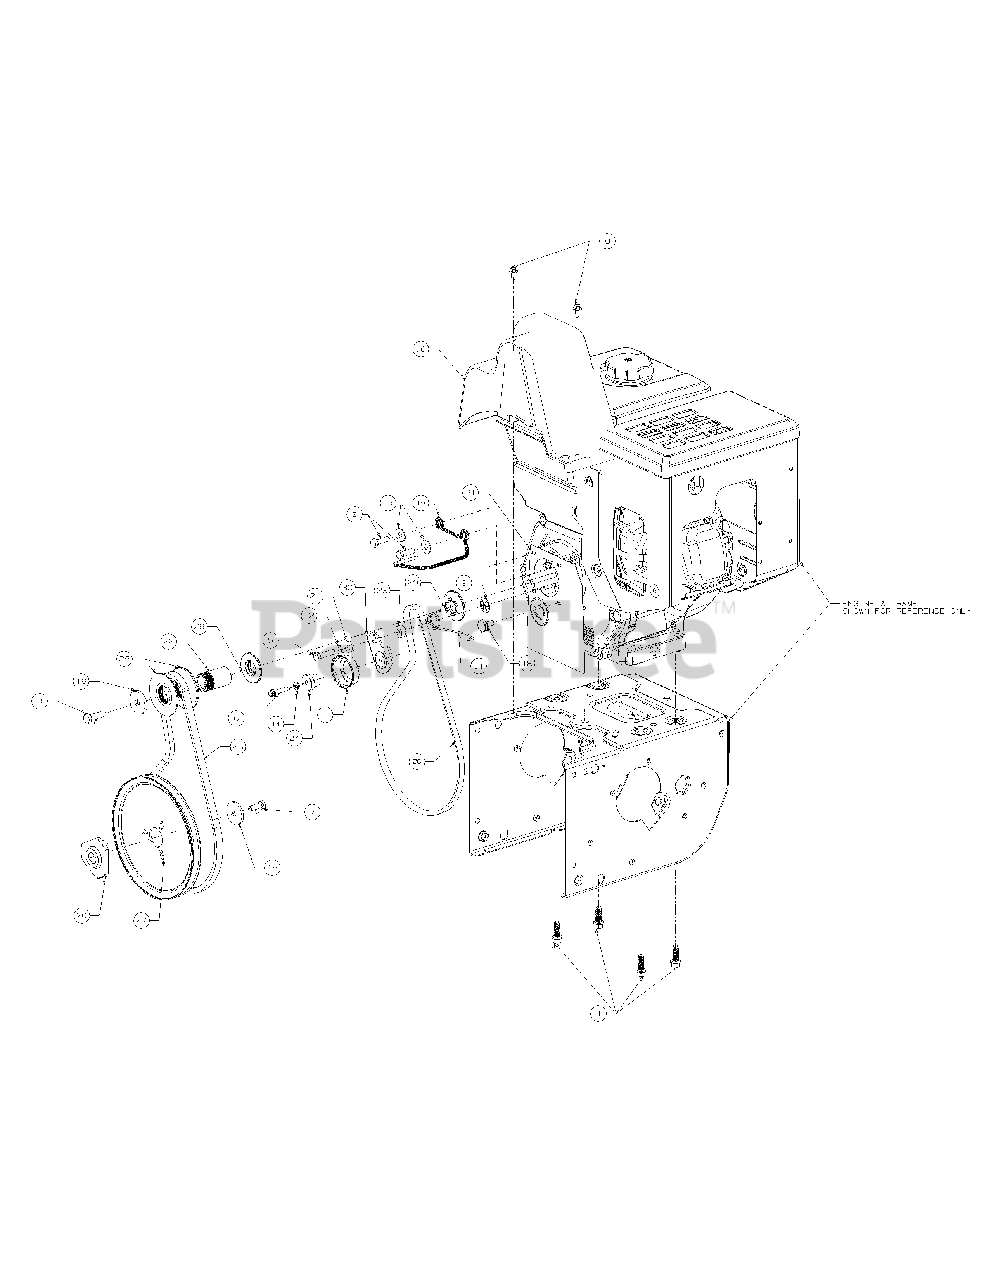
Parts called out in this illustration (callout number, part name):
1	Pulley Asm:Idler
2	Hhcs-5/16-24 X 1.0
3	Screw 3/8-24X1.25
4	Screw-Hex
5	Screw-Hex 5/16-24
6	Screw-Hex 1/4-20 X
7	Screw-Hex Cap 5/1
8	Screw Hex.Wash.Hd
9	Nut-Push On
10	Cover-Belt 4 Way
11	Spring-Torsion
12	Washer-Lock 5/16
13	Washer-Fl
14	Washer-Lock
15	Washer-Fl
16	Washer-Flat .45 X
17	Grease-
18	Screw-Shoulder
19	Guide-Belt
20	Pulley-Adapter .75
21	Spacer-Shoulder
22	Spacer-Pulley
23	Spacer-Idler Brkt
24	Spacer:Shoulder
25	Belt-.500 X 37.00 Lg
26	Belt-V Type 3/8 X 35.68"
27	Pulley-Auger 8.1 O
28	Pulley-Half 4L V
29	Pulley Half-3/8 V
30	Bracket-Idler Drive
31	Plate-Cove
